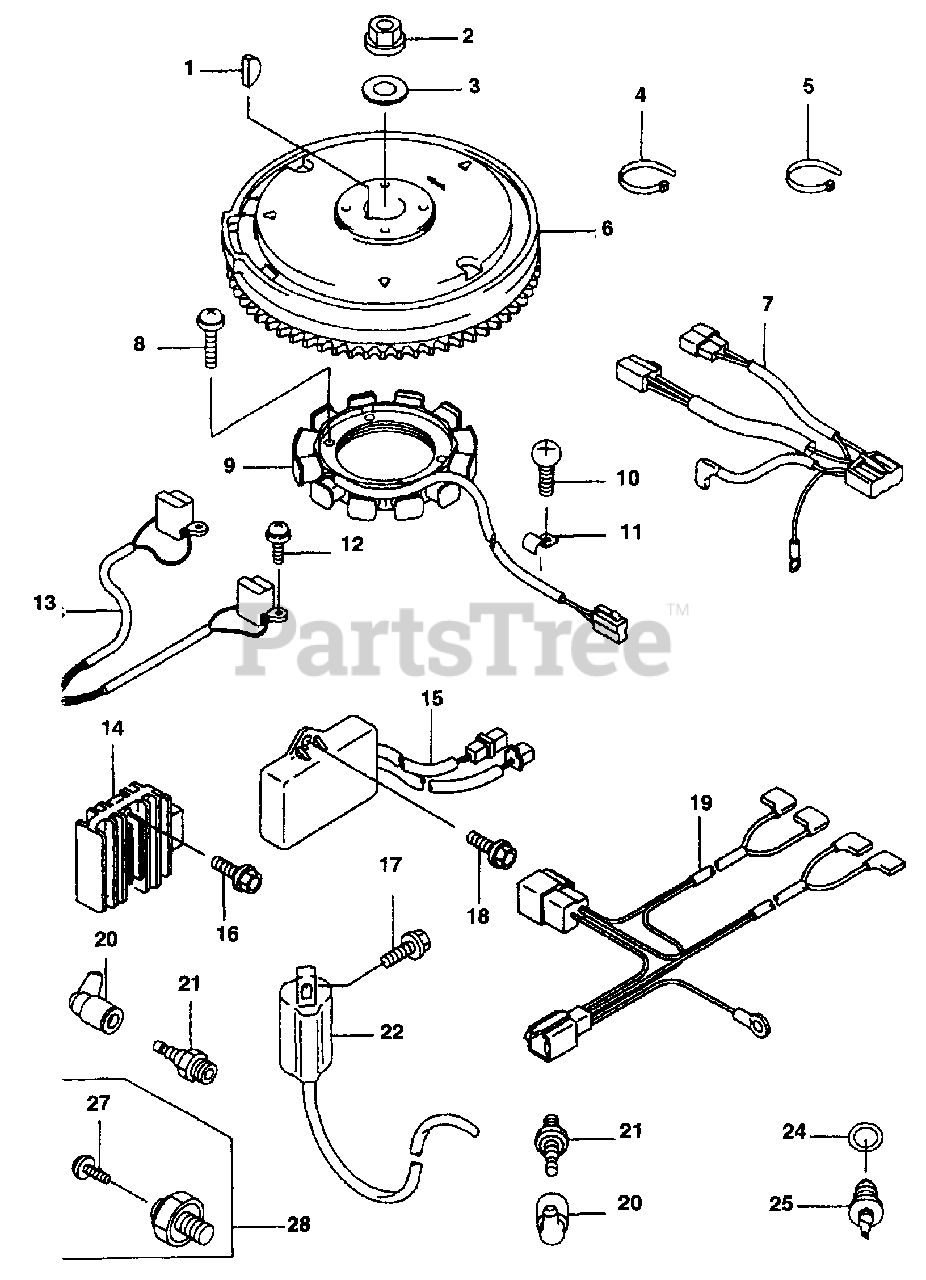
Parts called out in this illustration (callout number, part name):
6	Flywheel Ass'y
7	Harness
9	Charging Coil
13	Pulsing Coil
14	Regulator Voltage
15	Igniter
16	Flanged Bolt
17	Flanged Bolt
18	Flanged Bolt
20	Spark Plug Cap
21	Spark Plug
22	Ignition Coil
28	Switch
